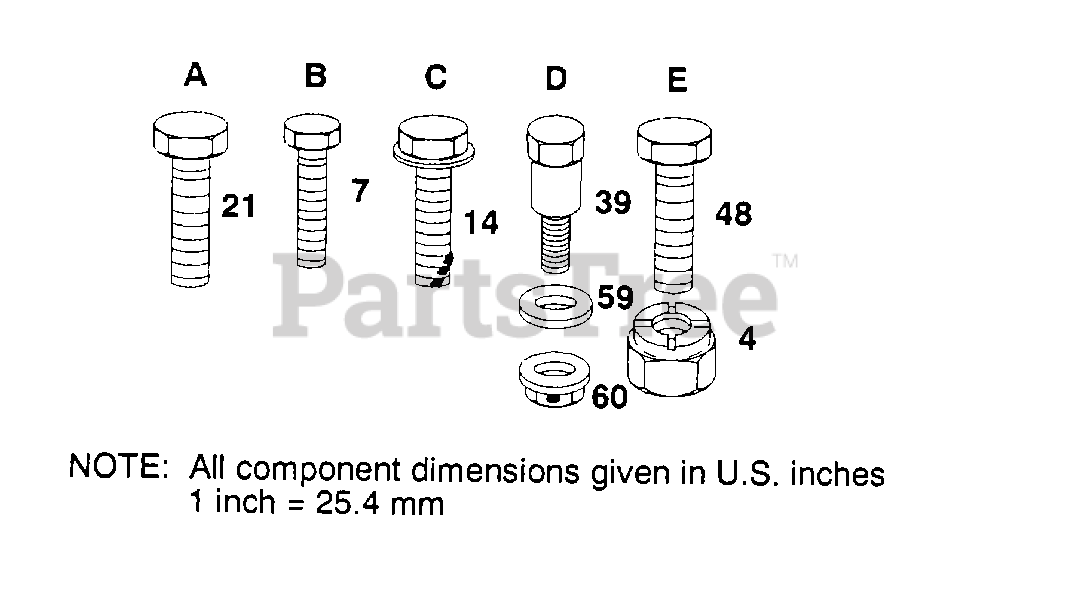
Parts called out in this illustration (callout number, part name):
7	SCREW
14	SCREW
21	SCREW LT
39	"BOLT, SHOULDER LT"
42	NUT
59	WASHER T
60	NUT SPECIAL T
